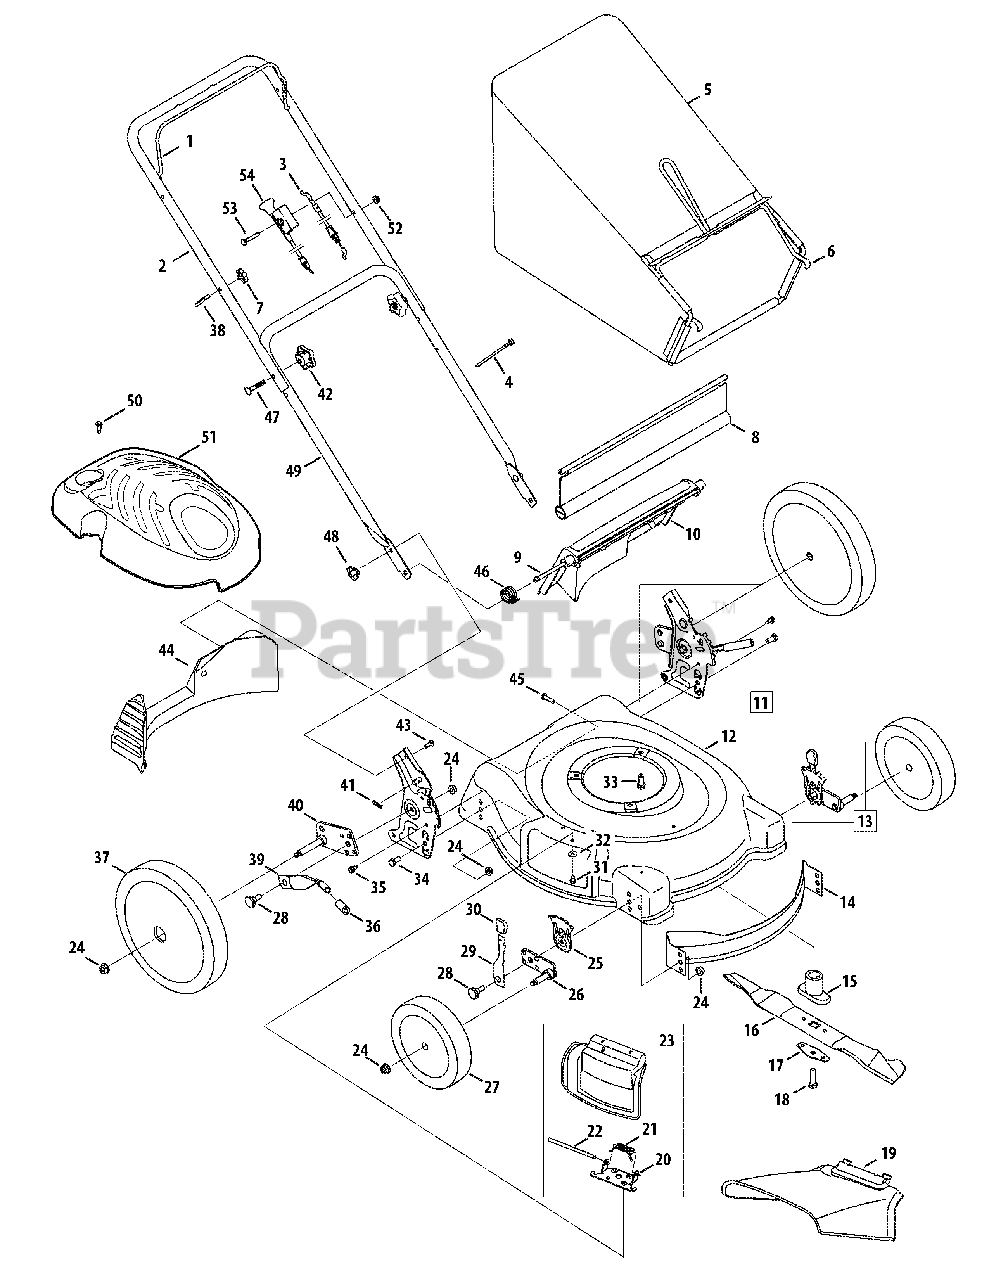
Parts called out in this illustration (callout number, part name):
1	Blade Control
2	Upper Handle
3	Control Cable
3	Control Cable (Engine w/Choke)
4	Cable Tie
5	Grass Bag
6	Grass Bag Frame
7	Handle Knob
8	Trail shield
9	Pivot Rod
10	Rear Discharge Door
11	Rear Handle Bracket Assy. - LH
11	Rear Handle Bracket Assy. - RH
12	Deck 21-inch - Red
12	Deck 21-inch - Green
13	Frt. Height Adj. Assy. - LH - 8" Whl.
13	Frt. Height Adj. Assy. - RH - 8" Whl.
13	Frt. Height Adj. Assy. - LH - 7" Whl.
13	Frt. Height Adj. Assy. - RH - 7" Whl.
14	Front Baffle
15	Blade Adapter w/Star
16	21-inch Mulching Blade
17	Bell Blade Support
18	Hex Screw, 3/8-24 x 2.5
19	Side Discharge Chute
20	Deflector Chute Adaptor
21	Torsion Spring
22	Hinge Pin
23	Mulch Plug Assembly
24	Flange Lock Nut 3/8-16
25	Height Adjustment Plate
26	Pivot Arm Assy. - RH - 8" Wheel
26	Pivot Arm Assy. - LH - 8" Wheel
26	Pivot Arm Assy. - RH - 7" Wheel
26	Pivot Arm Assy. - LH - 7" Wheel
27	Front Wheel, 8 x 1.8
27	Front Wheel, 7 x 1.8
28	Shoulder Scr., .5D x .385
29	Front Spring Lever
30	Height Adjust Knob
31	TT Screw, 1/4-20 x .500
32	Bell Washer
33	TT Screw, 3/8-16 x 1.0
34	Hex Screw, 3/8-16 x .75
35	TT Screw, 1/4-20 x .625
36	Foam Grip
37	Rear Wheel, 12 x 1.8
38	Eye Bolt
39	Rear Hi-Wheel Spring Lever
40	Rear Pivot Arm Assy - RH
40	Rear Pivot Arm Assy - LH
41	Hairpin Clip
42	Star Knob
43	Carriage Bolt ,1/4-20 x .75
44	Rear Baffle
45	Screw HL, 1/4-15 x 1.00
46	Torsion Spring - RH
47	Carriage Bolt, 5/16-18 x 2
48	Wing Nut
49	Lower Handle
50	Screw, HL, #12-16 x 1.00
51	Engine Shroud - Black
51	Engine Shroud - Gray
52	Nut, Flange Lock, 1/4-20
53	Screw, 1/4-20 x 1.50
54	Choke Cable
